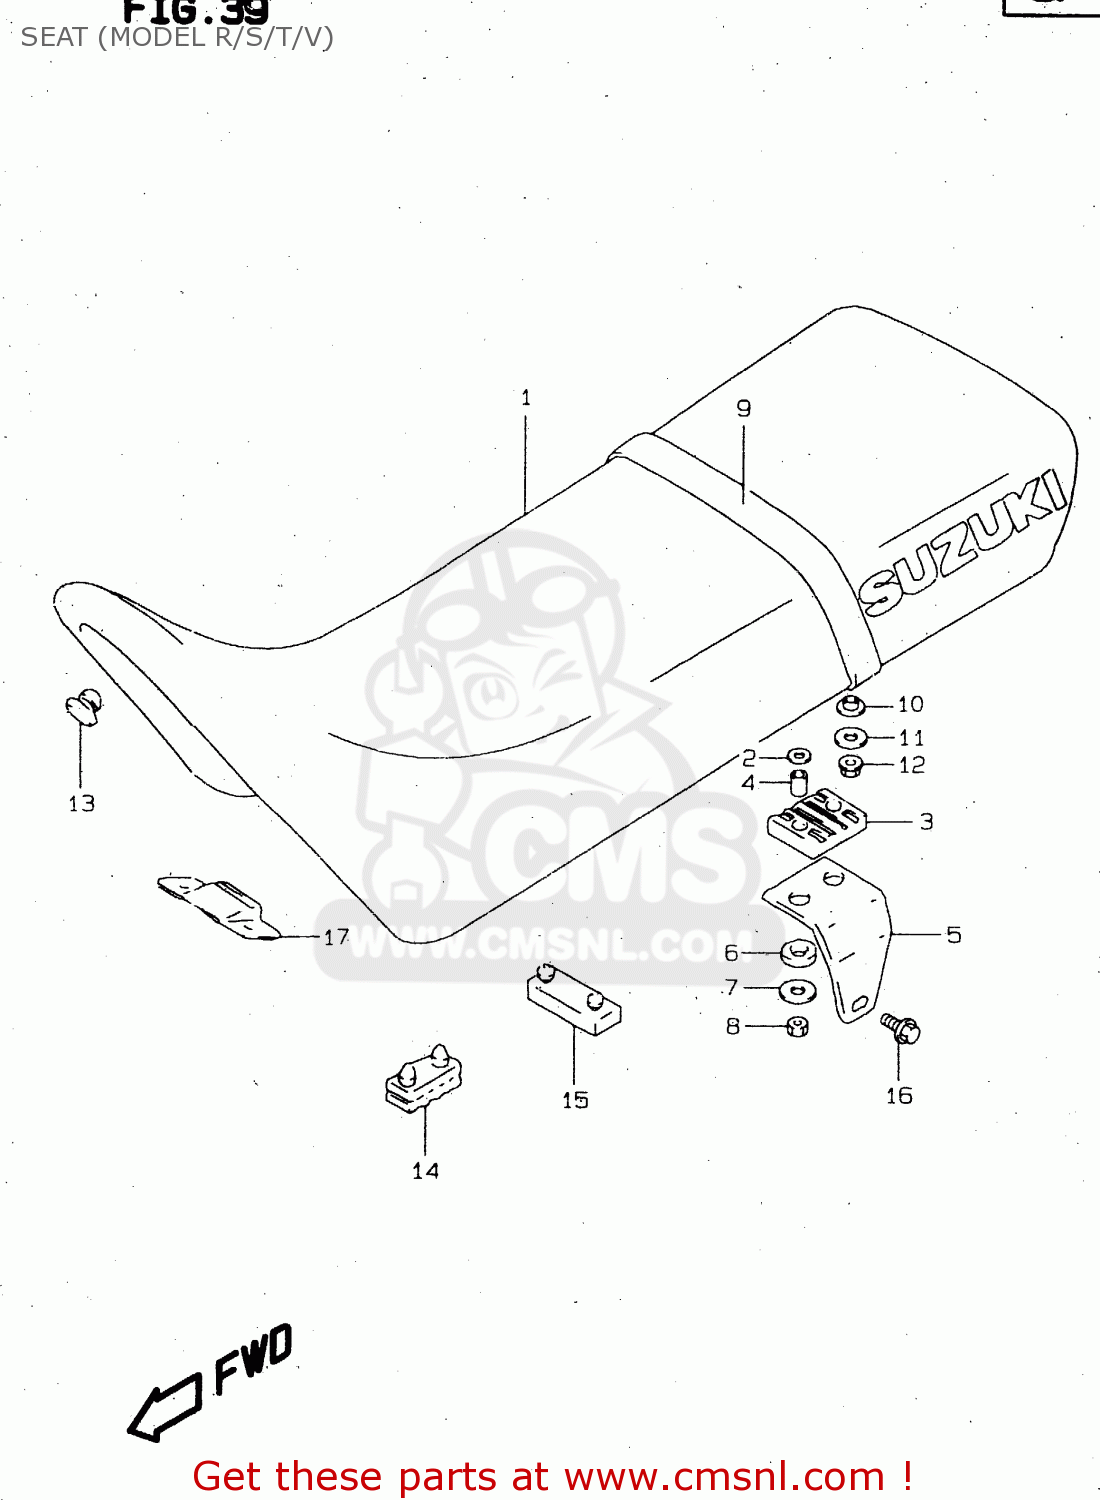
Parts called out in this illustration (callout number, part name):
1	SEAT SET
2	WASHER
3	CUSHION,FR PLATE
4	SPACER,SEAT BRACKET
5	BRACKET,SEAT
6	CUSHION,SEAT FR
7	WASHER
8	NUT
9	BAND,SEAT
10	WASHER
11	WASHER
12	NUT
13	CUSHION
14	CUSHION,SEAT(40X20X15)
15	CUSHION,SEAT
16	BOLT
17	PLATE,SEAT FR HOOK
